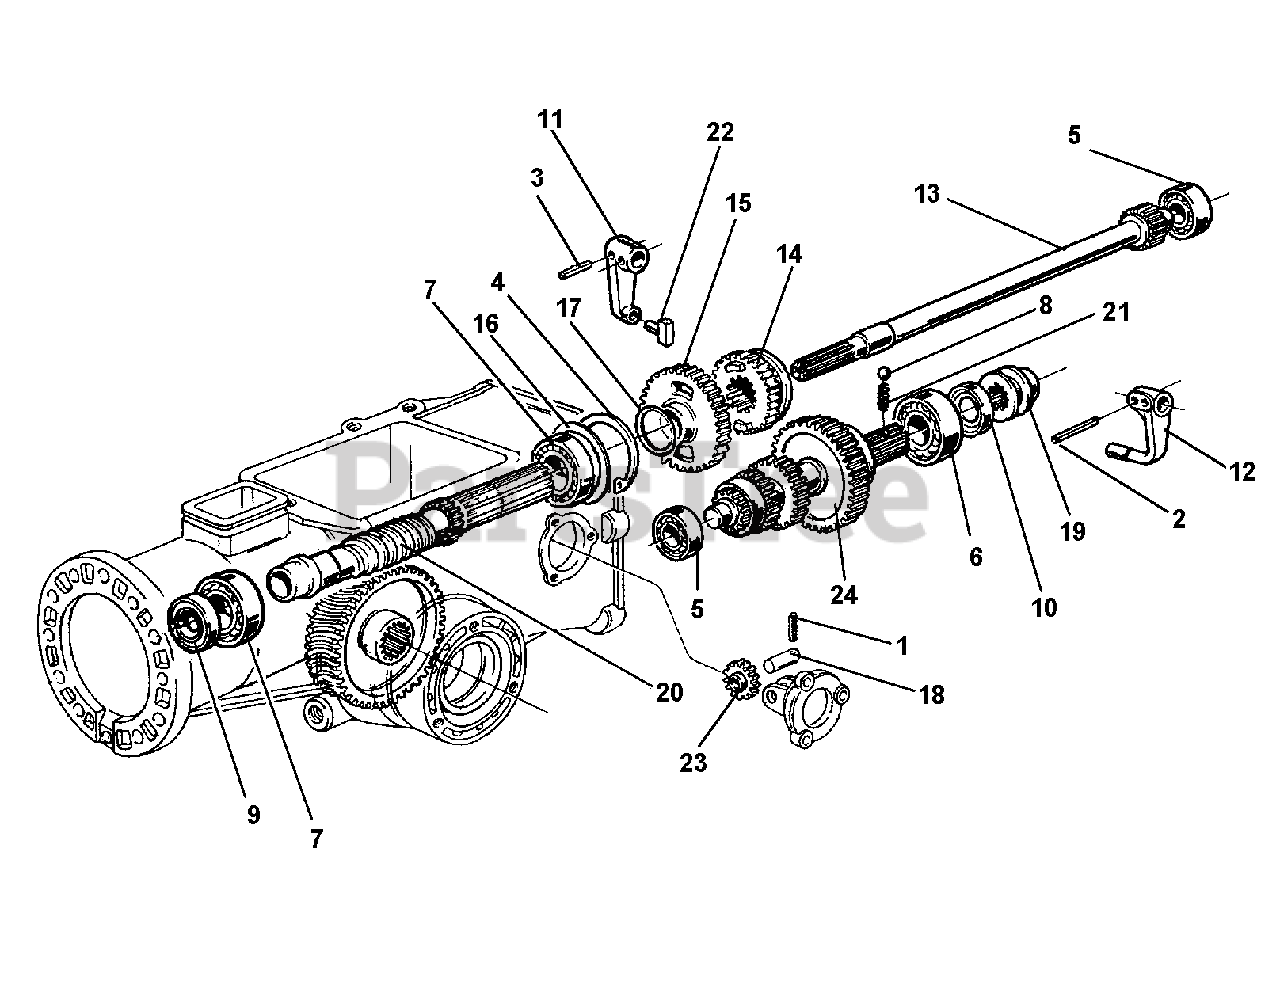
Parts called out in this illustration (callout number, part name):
1	PIN, LOCKING 2.5 X 22 DIN 1481
2	LOCKING PIN 4 X 20 SPIRAL
3	LOCKING PIN 4 X 24 SPIRAL
4	CIRCLIP, INTERN. D 52
5	BEARING 15 X 35 X 11 6202
6	BEARING 20 X 47 X 14 6204
7	BEARING 25 X 52 X 15 6205
8	BALL 1/4 RIV RB 6.35
9	SEAL, OIL 15 X 40 X 10 STANDARD
10	SEAL, OIL 20 X 35 X 7 STANDARD
11	LEVER, SPEED CHG SLDG GR
12	SLIDE LEVER
13	CLUTCH SHAFT
14	SLIDING GEAR S.C.
15	GEAR, I SPEED
17	WASHER 25 X 32 X 2 C-72
23	REVERSE SPEED GEAR
24	P.T.O. SHAFT
